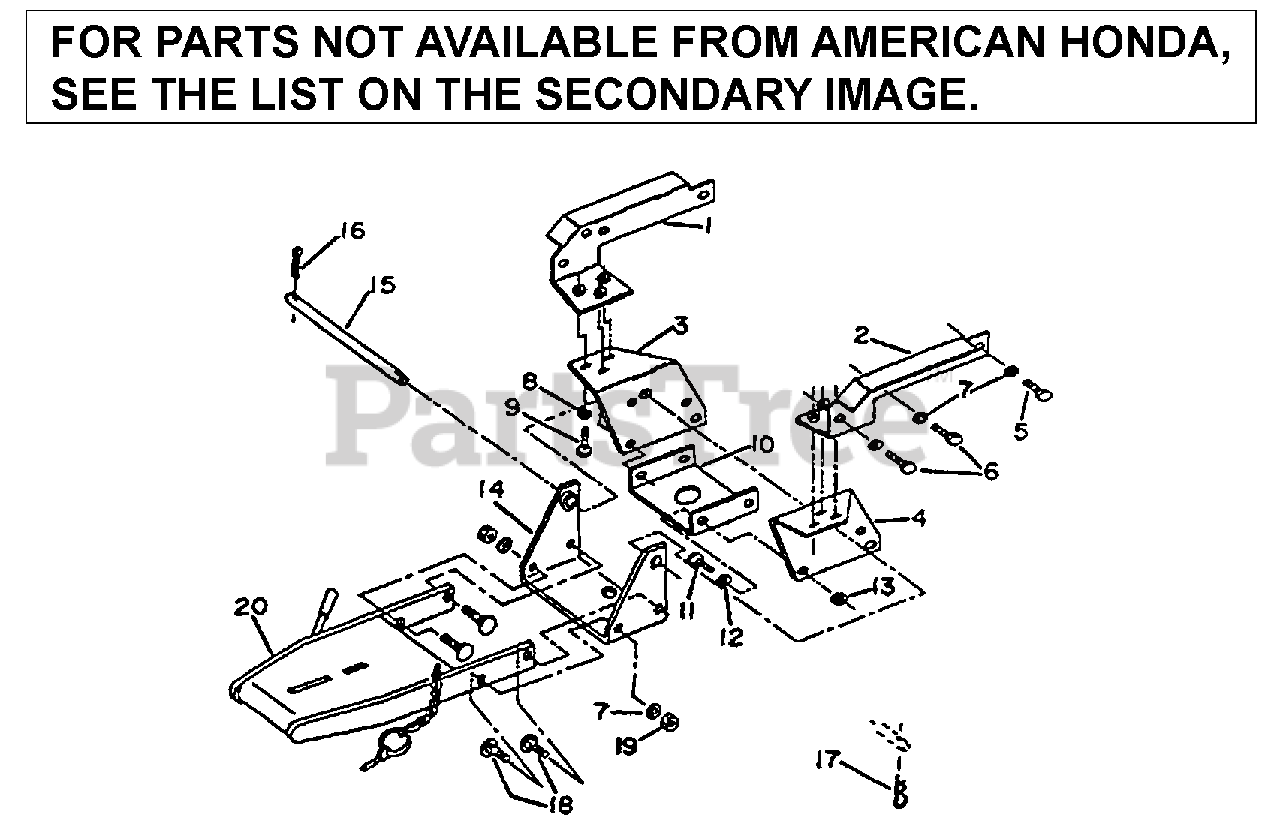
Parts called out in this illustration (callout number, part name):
1	BRACKET, R. FR. SUPPORT
2	BRACKET, L. FR. SUPPORT
3	PLATE, R. ATTACHING
4	PLATE, L. ATTACHING
5	BOLT, HEX. (10X25)
6	BOLT, HEX. (10X30)
10	PLATE, REINFORCEMENT
14	BRACKET, PIVOT
15	PIN (5/8X10-5/8")
17	PIN, HAIR (3X65)
